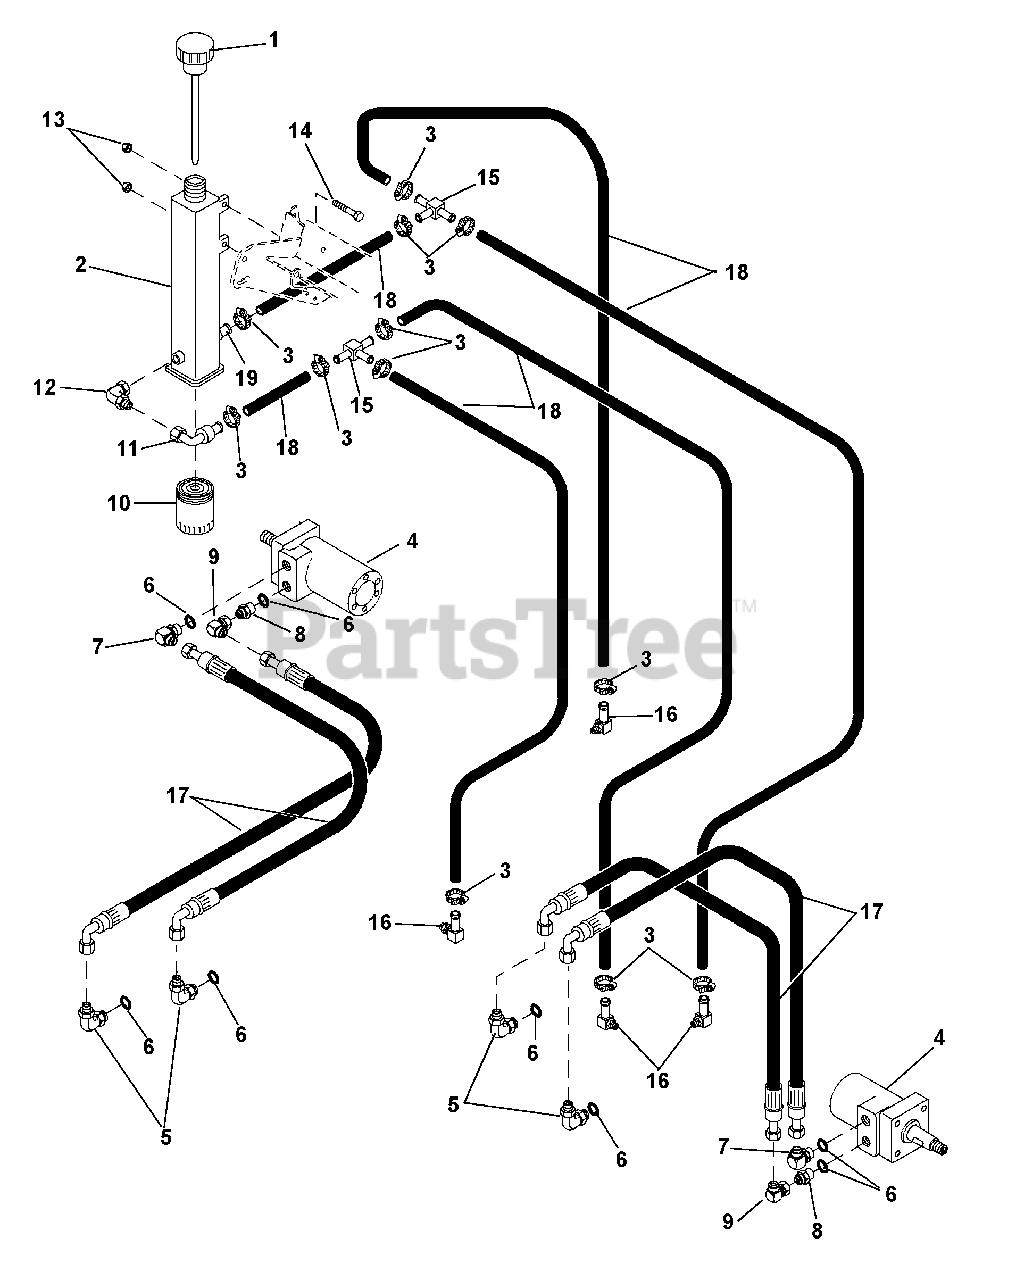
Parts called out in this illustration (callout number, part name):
2	Hydraulic Reservoir, Includes Decal
3	Hose Clamp
4	Wheel Motor
5	Fitting, Includes O-Ring
6	O-Ring, Included With Fitting
7	Adapter, 7/8 ORB x 3/4JIC x 90
8	Adapter, Hydraulic, 3/4-16MJIC x 7/8-14 MOR
9	Adapter, 3/4 FESW x 3/4 MJIC x 90
10	Element, Oil Filter
11	Elbow Fitting
12	Adapter 2503-6-6
13	Nut, Locking, Nylon 3/8-16
14	Bolt, Hex .38-16 x .75 Grade 5
15	Tee Fitting
16	Fitting, Adapter .562-18 Steel Thread
17	Hose, High Pressure
18	Hose, Return
19	Adapter, Straight Fitting
